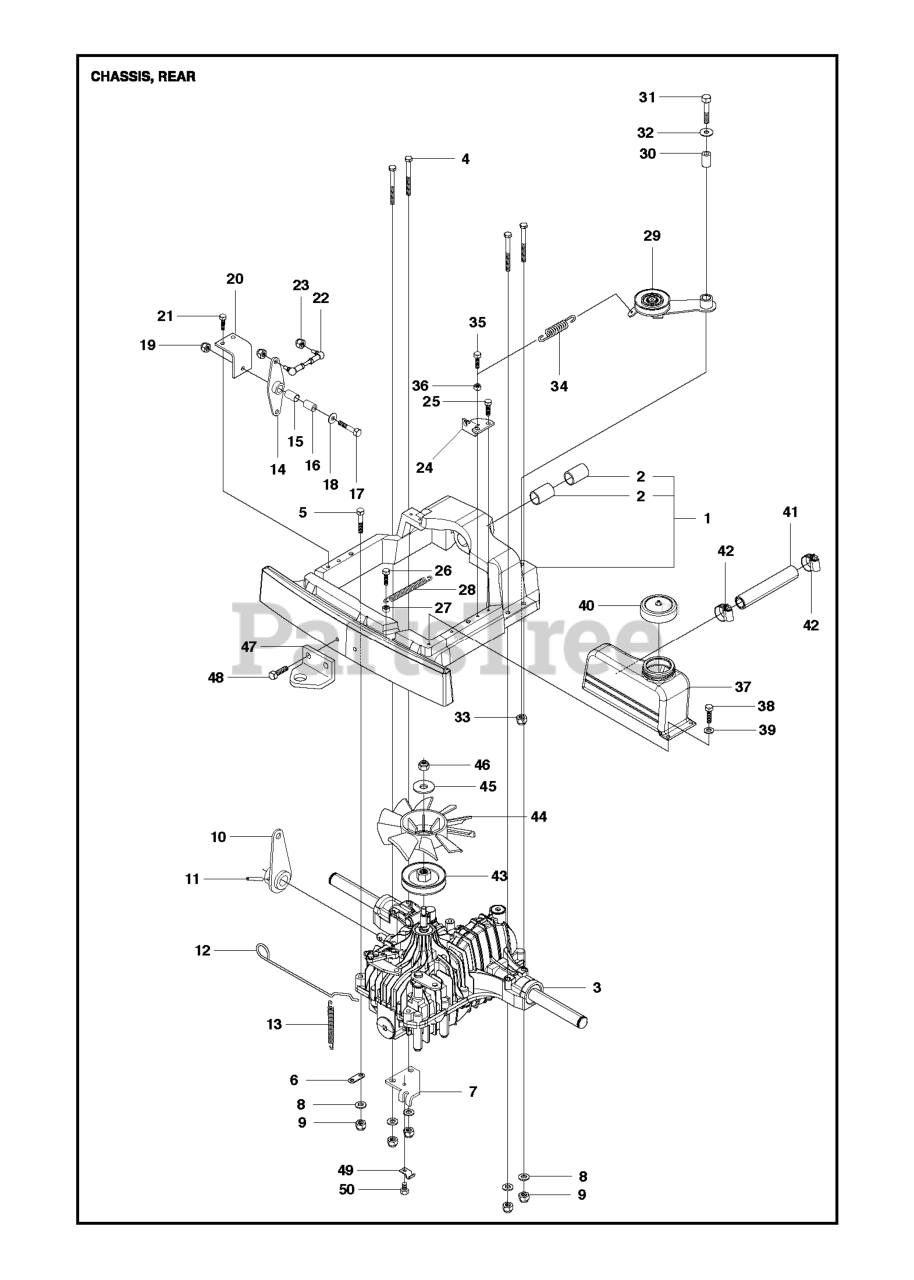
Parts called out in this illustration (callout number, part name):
8	WASHER BRB 8.4X17
9	LOCKNUT M8
14	ARM
17	SCREW
19	LOCKNUT M8
21	REPL BY 725 24 49-51
23	LOCKNUT M6
25	BOLT FLANGE - M6X20
33	LOCKNUT M8
38	BOLT FLANGE - M6X20
39	WASHER - 26X6.5X1.6
48	Screw M10x25
